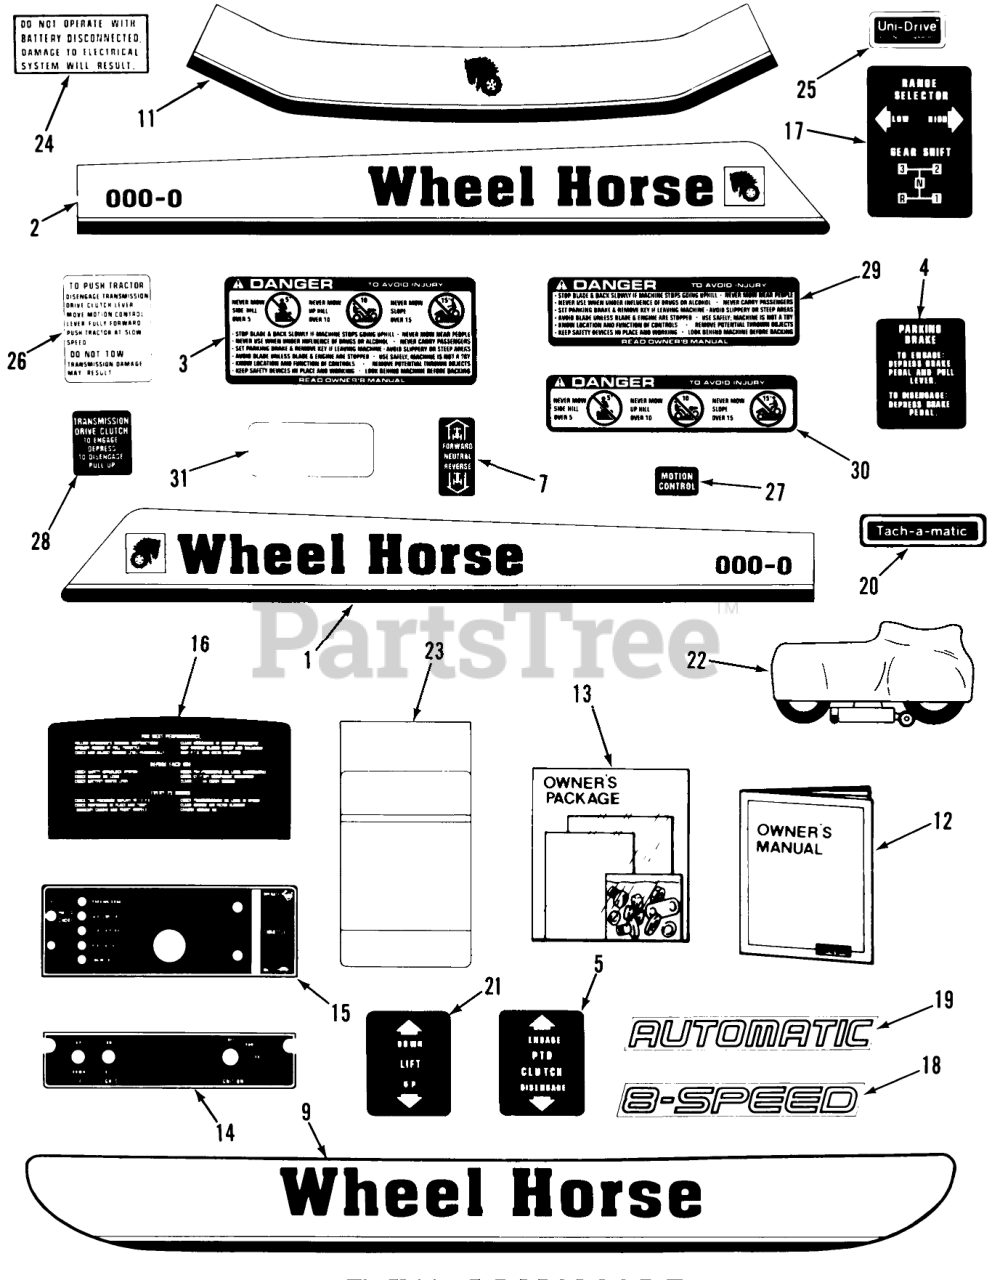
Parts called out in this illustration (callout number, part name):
1	DECAL HOOD RH
1	Decal-Hood RH 310 Only
1	Decal-Hood RH 312 Only
1	DECAL-HOOD RH
1	Decal-Hood RH 414 Only
1	Decal-Hood RH 416 Only
1	DECAL (RH)
2	DECAL HOOD LH
2	Decal-Hood LH 310 Only
2	Decal-Hood LH 312 Only
2	DECAL-HOOD LH
2	Decal-Hood LH 414 Only
2	Decal-Hood LH 416 Only
2	DECAL HOOD (LH)
3	DECAL-DANGER
4	DECAL-PARKING, BRAKE
5	DECAL PTO CLUTCH
7	Decal-Speed Control 312-A,418-A,418-C
9	Decal-Rear Fender
11	Decal-Hood Front
12	Owners Manual-Tractor
13	Loose Parts Package 308-8
13	Loose Parts Package 310-8
13	Loose Parts Package 312-8
13	Loose Parts Package 416-8
13	Loose Parts Package 418-8,418-A
13	Loose Parts Package 418-C
13	Loose Parts Package 312-A
13	Loose Parts Package 414-8
14	DECAL BACK PLATE
15	DECAL LOWER DASH
15	Decal-Lower Dash 310
16	Decal-Rear Hood
17	DECAL-SHIFT PATTERN
18	DECAL 8SPD
19	DECAL AUTOMATIC
20	DECAL-TACHAMATIC
21	DECAL-LIFT
22	Vinyl Tractor Cover
23	Decal-Maintenance
24	DECAL ELECT SYSTEM
25	Decal-Unidrive
26	DECAL-TO PUSH TRACT
27	Decal-Motion Control 312-A,418-A,418-C
28	Decal-Transmission Drive Clutch 312-A,418-A,418-C
29	Decal-Danger
30	Decal-Danger
31	DECAL-OVERLAY
